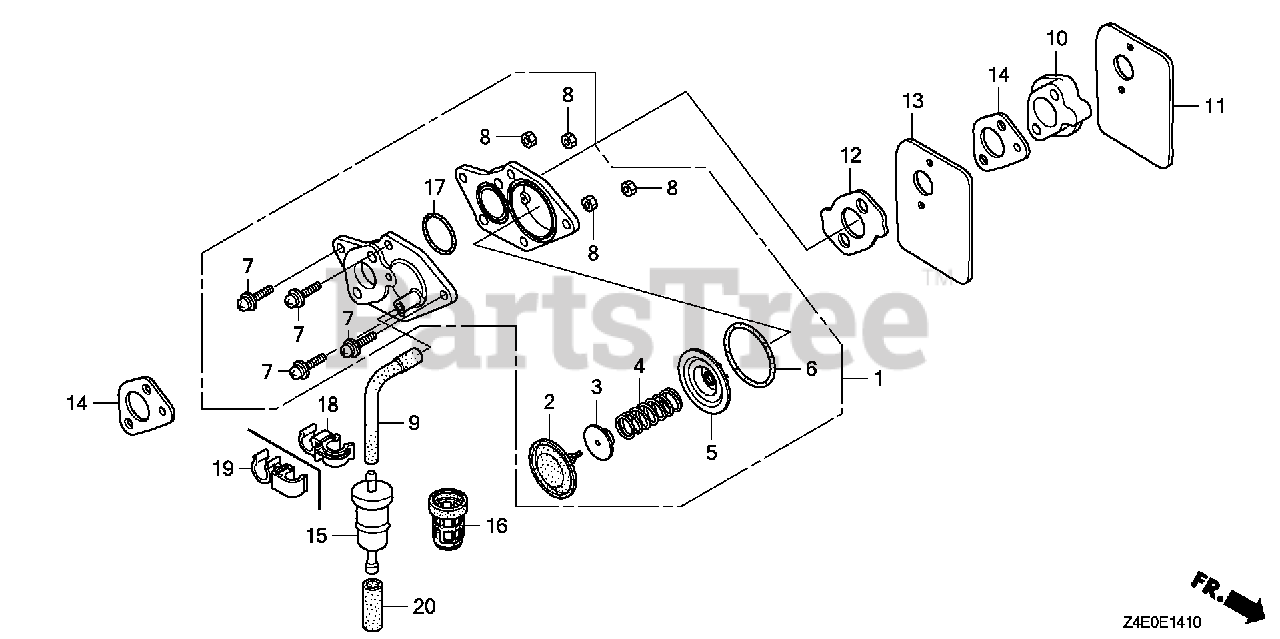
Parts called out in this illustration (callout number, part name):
1	PUMP ASSY., ACCELERATION
2	DIAPHRAGM, PUMP
3	RETAINER, DIAPHRAGM
4	SPRING
5	RETAINER, ACCELERATION PUMP
6	O-RING
7	SCREW ASSY.
8	NUT
9	TUBE, AIR VENT
14	GASKET, CARBURETOR
15	STRAINER, FUEL
16	SUSPENSION, STRAINER
17	O-RING (19.5X1.5)
19	CLIP, TUBE
20	BULK HOSE, VACUUM (7X3000) (7X35)
